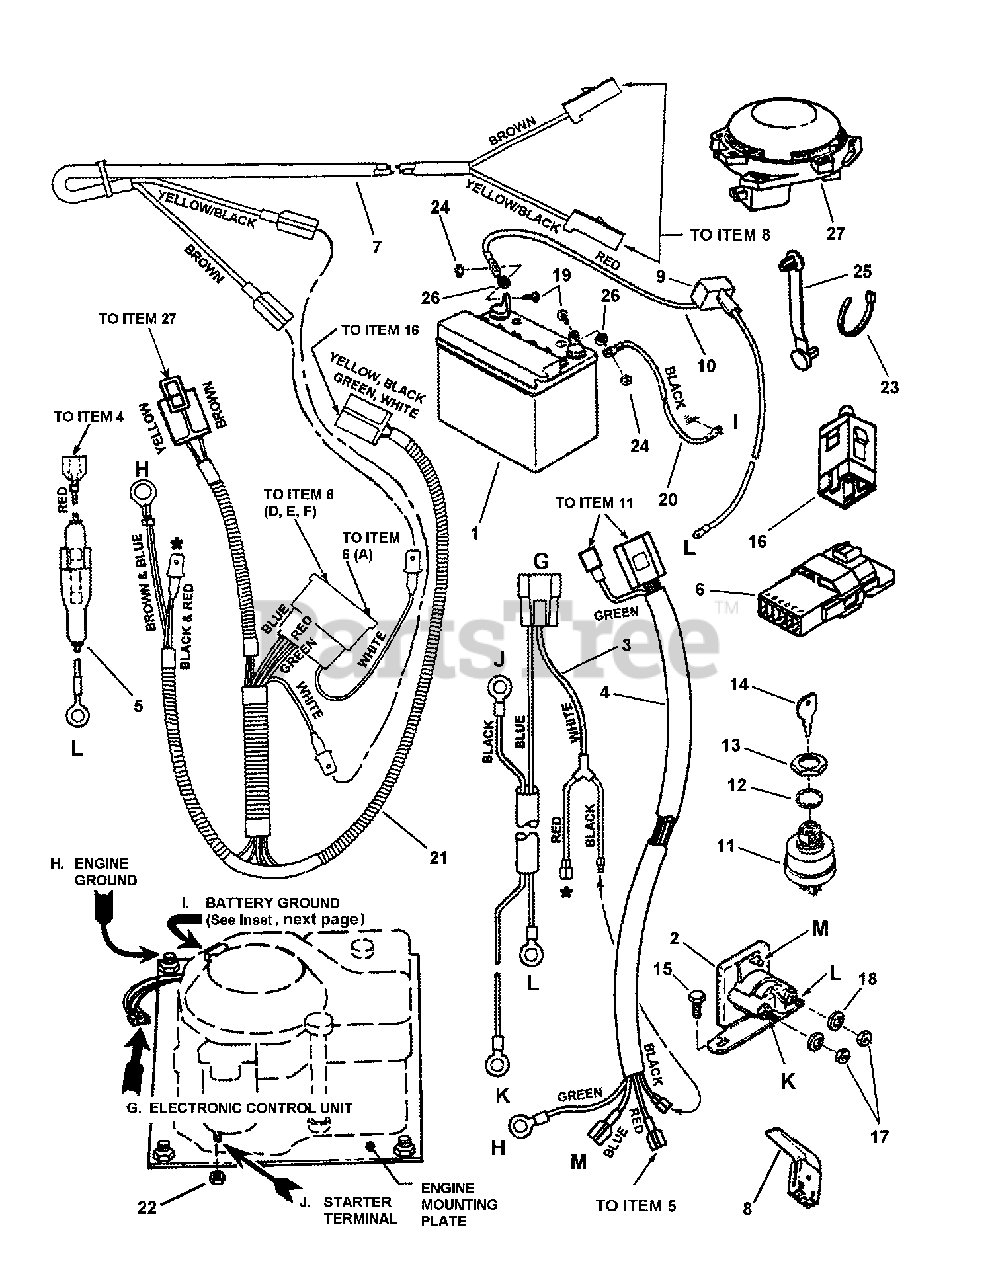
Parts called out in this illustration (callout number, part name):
1	KIT, 12 Volt Dry Charge Battery
2	SOLENOID, Super-Trombetta
3	HARNESS, Starter Wiring (Kohler Engines)
4	HARNESS, Ignition Wiring (15HP Kohler Engines)
5	HOLDER, Fuse (Includes Fuse)
6	INTERLOCK MODULE, Briggs & Kohler
7	HARNESS (Deck Interlock Wiring)
8	SWITCH, Deck Interlock (NO)
9	COVER, Battery Cable
10	WIRE, Positive (Red, 17" long)
11	SWITCH, Ignition, 4 Terminal, Indak
12	WASHER, 5/8" Internal Tooth Lock
13	NUT, 5/8-32 Hex
14	IGNITION KEY, Pair
15	SCREW, 1/4-20 x 1/2" Hex Washer Self-Tap
16	SWITCH, Operator Presence Control (OPC) Traction (NC/NO)
17	NUT, 1/4-20 Hex, GR 5 or B
18	WASHER, 1/4" Internal Tooth Lock
19	SCREW, 1/4-20 x 5/8" Hex Head Cap, GR 5
20	WIRE, Negative, Black (15" long)
21	HARNESS, Operator Presence Control (OPC) Wire
22	NUT, 1/4-20 Hex, GR 5 or B
23	CABLE TIE, 7"
24	NUT, 1/4-20 Hex Center Lock, GR 5 or B
25	CABLE TIE, 3.19" long
26	RETAINER, 1/4" Bolt
27	SWITCH, Seat (NC)
